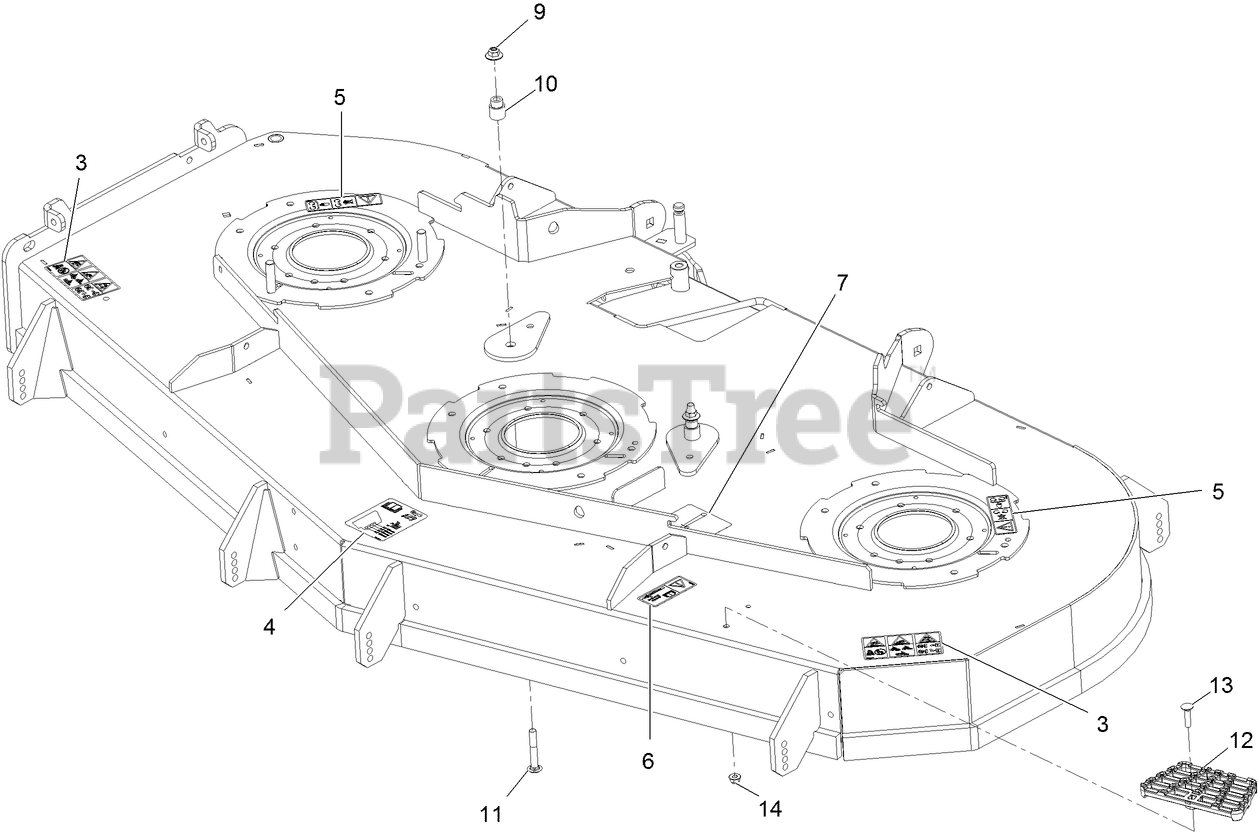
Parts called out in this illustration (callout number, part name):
3	DECAL-DANGER THROWN OBJECTS
4	DECAL-ROLLER, ANTI-SCALP
5	DECAL-COVER, MISSING
6	DECAL-TORQUE, BOLT
7	DECAL-BELT ROUTING
9	Nut-Nyloc 3/8-16 Flg
10	BUSHING-IDLER
11	SCREW-CARR
12	STEP-DECK
13	Bolt-Carriage 5/16-18 X 1 1/4
14	NUT-HF, NI
